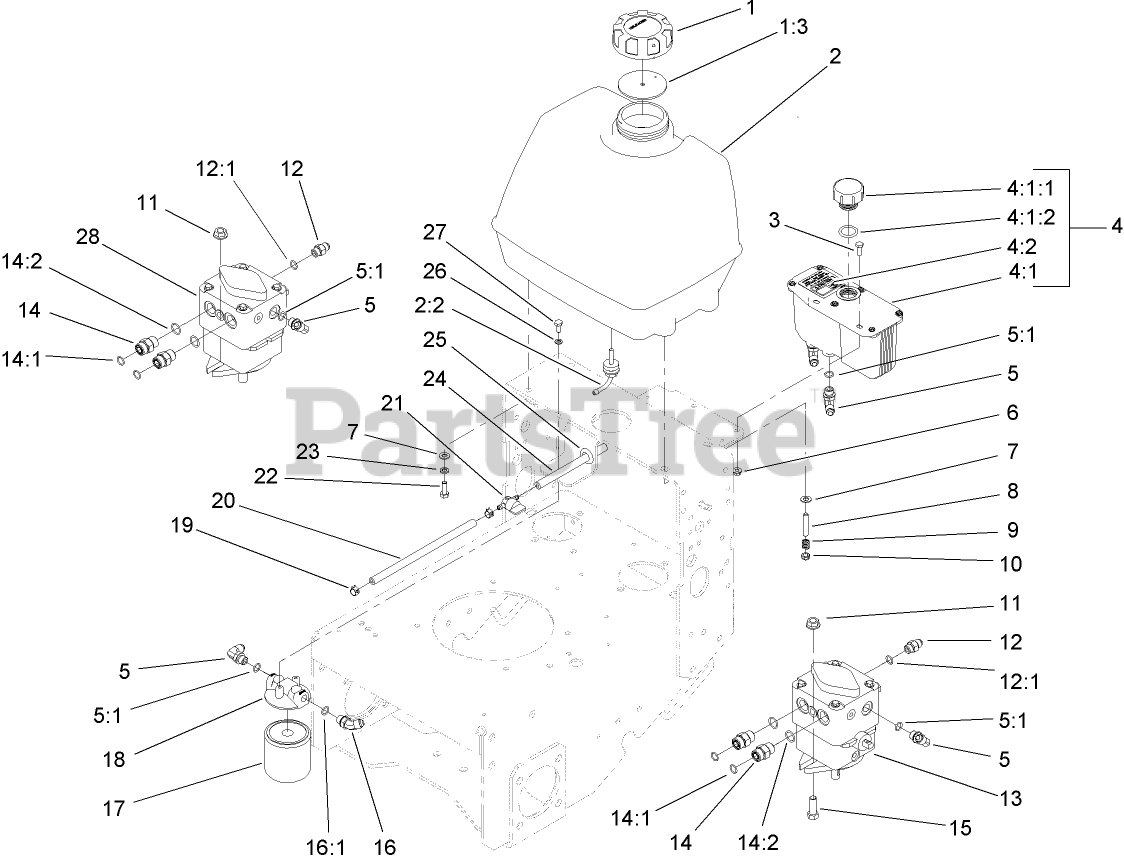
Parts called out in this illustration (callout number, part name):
1	GAS CAP ASM
1:3	GASKET-CAP, GAS
2	FUEL TANK ASM
2:2	FITTING-FUEL, BULKHEAD
3	SCREW-HH
4	HYD Reservoir ASM
4:1	Reservoir-HYD
4:1:1	CAP-RESERVOIR, HYD
4:1:2	GASKET-CAP
4:2	DECAL-TANK, HYD
5	FITTING-ELBOW, 90 DEG
5:1	O-RING
6	NUT-HF
7	WASHER-PLAIN
8	STUD-THREADED
9	SPRING-TANK, FUEL
10	NUT-LOCK, NI
11	NUT-HF
12	FITTING-STRAIGHT
12:1	O-RING
13	PUMP-HYD
14	FITTING-STRAIGHT
14:1	O-RING
14:2	O-RING
15	SCREW-HH
16	FITTING-ELBOW, 45 DEG
16:1	O-RING
17	FILTER-OIL, HYD
17	FILTER-OIL, HYD (WINTER)
18	HEAD-FILTER
19	CLAMP-HOSE
20	HOSE-FUEL
21	VALVE-FUEL
22	SCREW-HH
23	WASHER-LOCK
24	HOSE-FUEL
25	GROMMET
26	WASHER-LOCK
27	SCREW-HH
28	PUMP-HYD
